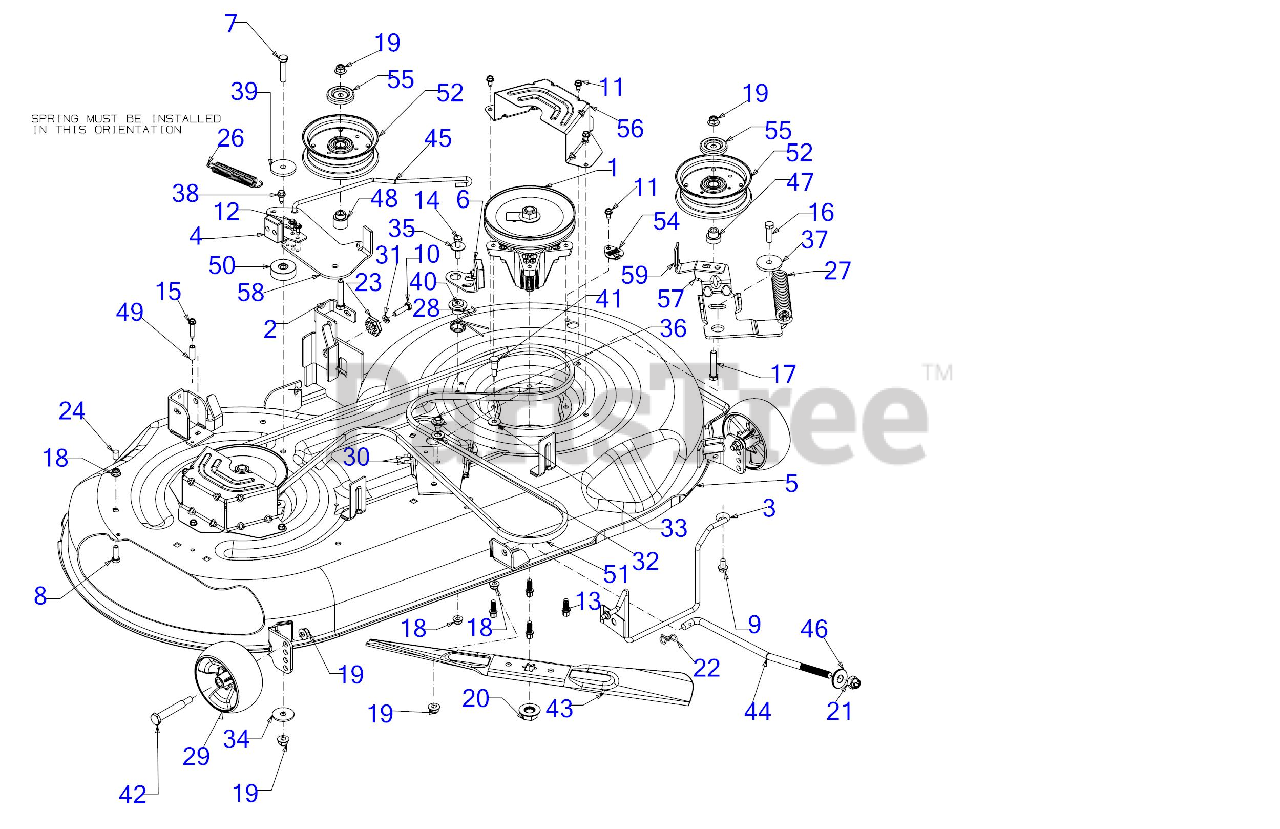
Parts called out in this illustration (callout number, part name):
1	SPINDLE ASSEMBLY
1	Troy-Bilt 46" SPINDLE ASSEMBLY (06989)
3	BELT KEEPER BRACKET ASSEMBLY
4	DECK BRAKE ASSEMBLY (RH)
5	46" DECK SHELL
6	DECK BRAKE ASSEMBLY
7	HEX SCREW 3/8-16 x 1.75 GR5
8	SCREW 5/16-18 x 1.0 GR5
9	SCREW 5/16-18 x .750
10	SCREW 5/16-18 x 1.25 GR5
11	SCREW 1/4-20 X.500
12	SCREW M6-1 x .625
13	SCREW 5/16-18 X .875
14	SCREW 5/16-18 x 1.5 LG
15	SCREW 1/4-20 x 1.25
16	SCREW 3/8-16 x 1.25 GR5
17	SCREW 3/8-16 x 2.0 GR 8
18	FLANGE LOCK NUT 5/16-18
20	HEX NUT
22	PIN:COTTER
23	DECK ADJUSTMENT
24	VINYL CAP
26	EXTENSION SPRING
27	EXTENSION SPRING
28	TORSION SPRING
29	DECK WHEEL
29	WHEELS-DELUXE 5"
30	BUMPER, .62 DIA x .3
31	LOCK WASHER 5/16
32	FLAT WASHER.469 ID x .88 OD
33	FLAT WASHER
34	FLAT WASHER .406X1.500X.105
35	FLAT WASHER 344X1.00
36	SHOULDER SCREW .43X.29X5/16-18 TT
37	SHOULDER SPACER
38	SHOULDER SCREW
39	SHOULDER SPACER
40	DOUBLE SHOULDER SPACER .750 X .135
41	SHOULDER SCREW
42	SHOULDER BOLT
43	23.25" BLADE (2N1)
43	Genuine Factory Parts 46" BLADE SET(STAR
43	46" 6 PT STAR LOW LIFT/SAND BLADE
43	Cub Cadet 46" LOWLIFT BLADE SET
43	Genuine Factory Parts 46" LOWLIFT BLADE SET
43	23.25" BLADE (2N1) (XTREME)
43	Cub Cadet BLADE SET (XTREME) 46" CUB 04290-X
44	DECK FRONT LIFT ROD
45	DECK BRAKE ROD
46	DECK LIFT PIVOT CUP
47	SHOULDER SPACER
48	SHOULDER SPACER
49	SPACER
50	SPACER .385ID x 1.75OD x .585THK
51	V-BELT A SEC x 103.24
51	Genuine Factory Parts 46" DECK DRIVE BELT
52	IDLER PULLEY 4.50" DIA
54	DECK WASH PLUG
55	IDLER PULLEY CAP
57	IDLER BRACKET 46T (LH)
58	DECK IDLER BRACKET
